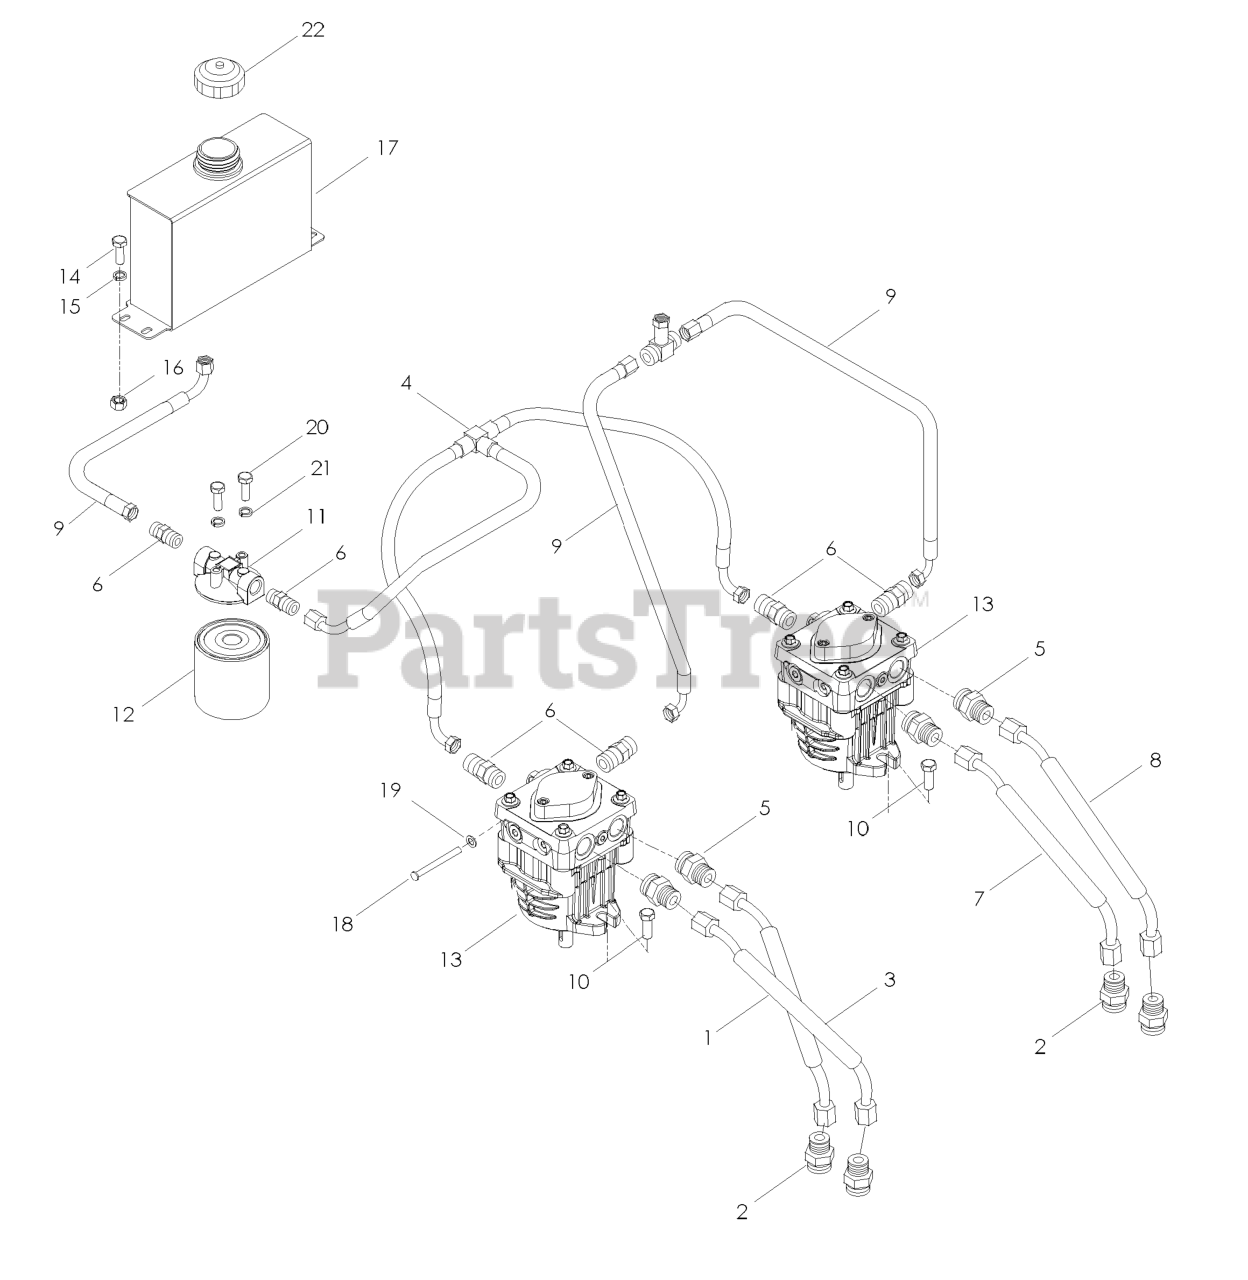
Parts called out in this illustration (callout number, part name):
1	HOSE, RPB-MA LINE
3	HOSE, RPA-MB LINE
4	HOSE, T-ASM SUPPLY
5	FITTING, STRAIGHT F6400-8-8-0
6	FITTING HYDRAULIC
7	HOSE, LPB-MB LINE
8	HOSE, LPA-MA LINE
9	HOSE, RETURN LINE
10	4CS 3/8C X 1 SERRATED HEAD
11	FILTER HEAD
12	HYDRAULIC OIL FILTER
13	HG_PUMP, 10CC W/O FAN OR RTN
14	HCS 1/4C X 3/4 HCS
15	WASHER 1/4 FLAT
16	NUT 1/4C CENTER LOCK
17	OIL TANK BLK
18	CLEVIS PIN
19	NUT PUSH
20	HCS 1/4C X 5/8
21	LOCKWASHER 1/4"
22	HYDRAULIC CAP
